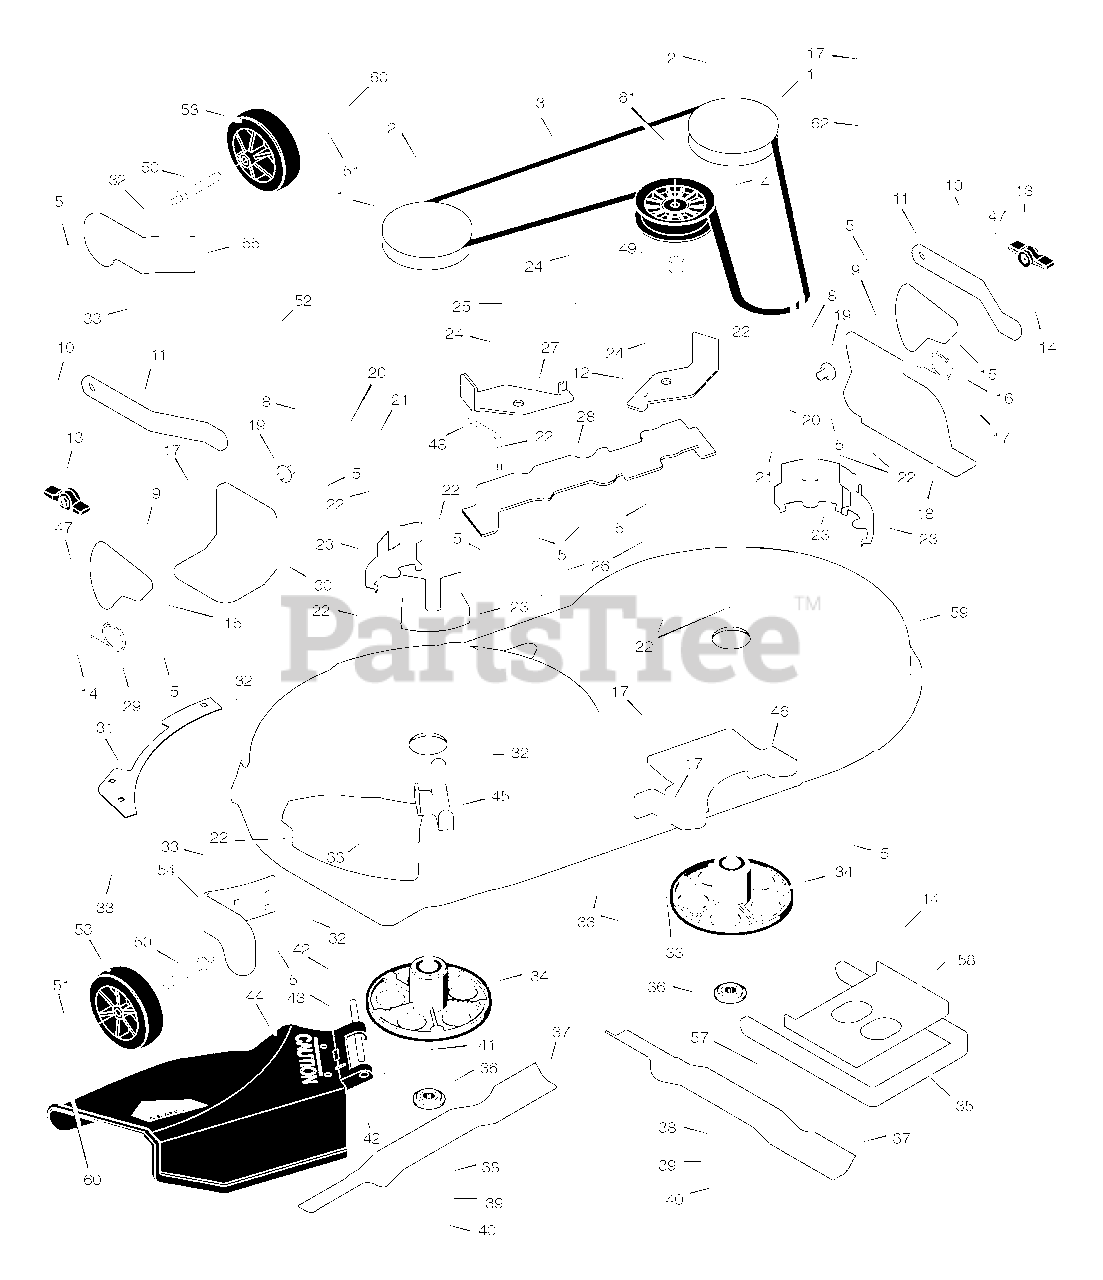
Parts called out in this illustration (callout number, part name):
1	Pulley, Jackshaft
2	Nut, Hex
3	Belt, Mower Drive
4	Pulley, Idler
5	Nut, Flange
8	Link, Lift
9	Pad, Friction
10	Bolt, Shoulder
11	Bracket, Suspension
12	Pad Assembly, Left Brake
13	Knob
14	Bolt, Shoulder
15	Plate, Suspension
17	Nut, Flange
18	Bracket, Suspension
19	Pin, Hanger
21	Pin, Hair
22	Bolt
23	Cover, Pulley
24	Bolt, Shoulder
25	Arm, Idler
27	Pad Assembly, Right Brake
28	Bracket, Brake
30	Bracket, Suspension
32	Nut, Flange
33	Bolt, Carriage
34	Mandrell Housing
35	Bracket, Suspension
36	Adapter, Blade
42	Cap, Push On
43	ROD, Deflector
44	Deflector Assembly
45	Bracket, Deflector Hinge
46	Bracket, Front Hanger
48	Guide, Belt
50	BOLT, Gauge Wheel
52	Spring, Extension
53	Wheel, Gage
54	Bracket, Right Wheel
55	Bracket, Left Wheel
59	Housing, Blade, Complete (NO LONGER AVAILABLE)
59	Housing, Blade (Housing Only)
60	Ring, Locking
61	Nut, Flange
62	Guide, Belt
